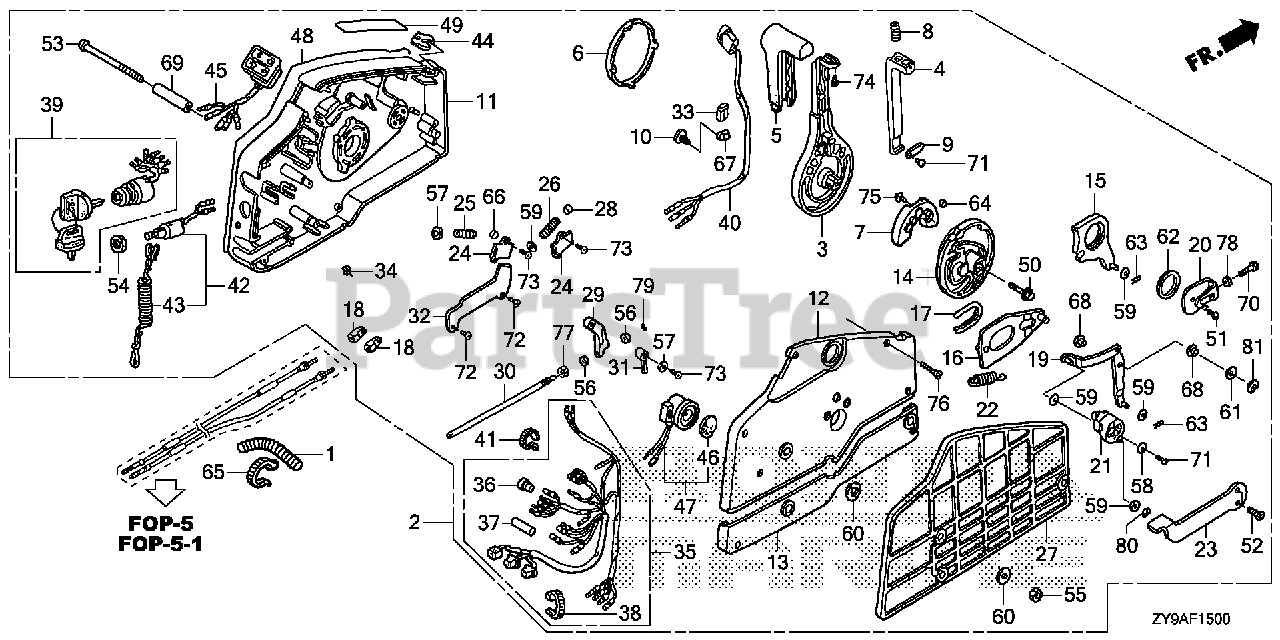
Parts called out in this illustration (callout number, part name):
1	TUBE, CORRUGATE (28MM)
2	BOX ASSY., REMOTE CONTROL (NHK MEC)
2	BOX ASSY., REMOTE CONTROL (TROLLING CONTROL)(NHK MEC)
3	HANDLE, REMOTE CONTROL
4	LEVER, HANDLE LOCK
5	GRIP, REMOTE CONTROL HANDLE
6	CAP, HANDLE
7	BLOCK, NEUTRAL LOCK
8	SPRING, REMOTE CONTROL HANDLE
9	PLATE, LEVER SETTING
10	CLAMP, HARNESS
11	HOUSING, REMOTE CONTROL BOX (A)
12	HOUSING, REMOTE CONTROL BOX (B)
13	HOUSING, REMOTE CONTROL BOX (C)
14	WHEEL, CONTROL
15	ARM, SHIFT LINK
16	PLATE, SLIDING
17	COLLAR, SLIDING PLATE
18	PIVOT, SHIFT
19	ARM, LINK JOINT
20	BRACKET, LINK JOINT
21	WHEEL, ACCELERATOR
22	SPRING, ACCELERATOR WHEEL
23	LEVER, IDLE
24	PLATE, SPRING SETTING
25	SPRING, SHIFT CLICK
26	SPRING, CHOKE RETURN
27	SPACER, REMOTE CONTROL BOX
28	SPACER, CLICK SPRING
29	BLOCK, THROTTLE FRICTION
30	BOLT, FRICTION
31	SPACER, NEUTRAL SWITCH
32	CLAMP, POWER TILT CORD
33	PIPE, HARNESS GUIDE
34	SPACER, CABLE CLAMP
35	CABLE ASSY., REMOTE CONTROL (B)
36	PLUG, CONNECTOR (INNER)
37	PLUG, CONNECTOR (OUTER)
38	TIE, CABLE (2.4X92) (NATURAL)
39	SWITCH ASSY., COMBINATION
40	SWITCH ASSY., POWER TRIM-TILT
41	BAND (BLACK 3.5X140)
42	SWITCH ASSY., EMERGENCY STOP
43	WIRE, EMERGENCY
44	CLIP, EMERGENCY LOCK
45	LAMP ASSY., INDICATION
46	PLATE, TURN SIGNAL BUZZER
47	BUZZER, WARNING
48	PLATE, REMOTE CONTROL (COUTION COLOR=RED & YELLOW)
49	MARK, FAST IDLE
50	BOLT, FLANGE (8X35)
51	SCREW, PAN (6X10)
52	SCREW, FLAT (5X12)
53	SCREW (6X95)
54	NUT, HEX. (16MM)
55	NUT, HEX. (6MM)
56	WASHER, PLAIN (4MM)
57	WASHER, PLAIN (5MM)
58	WASHER, PLAIN (5MM)
59	WASHER, PLAIN (6MM)
60	WASHER (6MM)
61	WASHER, PLAIN (8MM)
62	WASHER (28MM)
63	PIN, LOCK (6MM)
64	PIN (6X6)
65	BAND, SELF-LOCK
66	ROLLER, CLICK
67	CLIP, WIRE HARNESS (6.3MM)
68	COLLAR, LINK JOINT
69	COLLAR, DISTANCE (6X10X43.5)
70	BOLT, HEX. (5X16)
71	SCREW, PAN (5X10)
72	SCREW, TAPPING (5X8)
73	SCREW, TAPPING (5X10)
74	SCREW, TAPPING (5X12)
75	SCREW, TAPPING (6X16)
76	SCREW, TAPPING (5X25)
77	NUT, HEX. (6MM)
78	NUT, HEX. (5MM)
79	E-RING (3MM)
80	E-RING (4MM)
81	E-RING (7MM)
